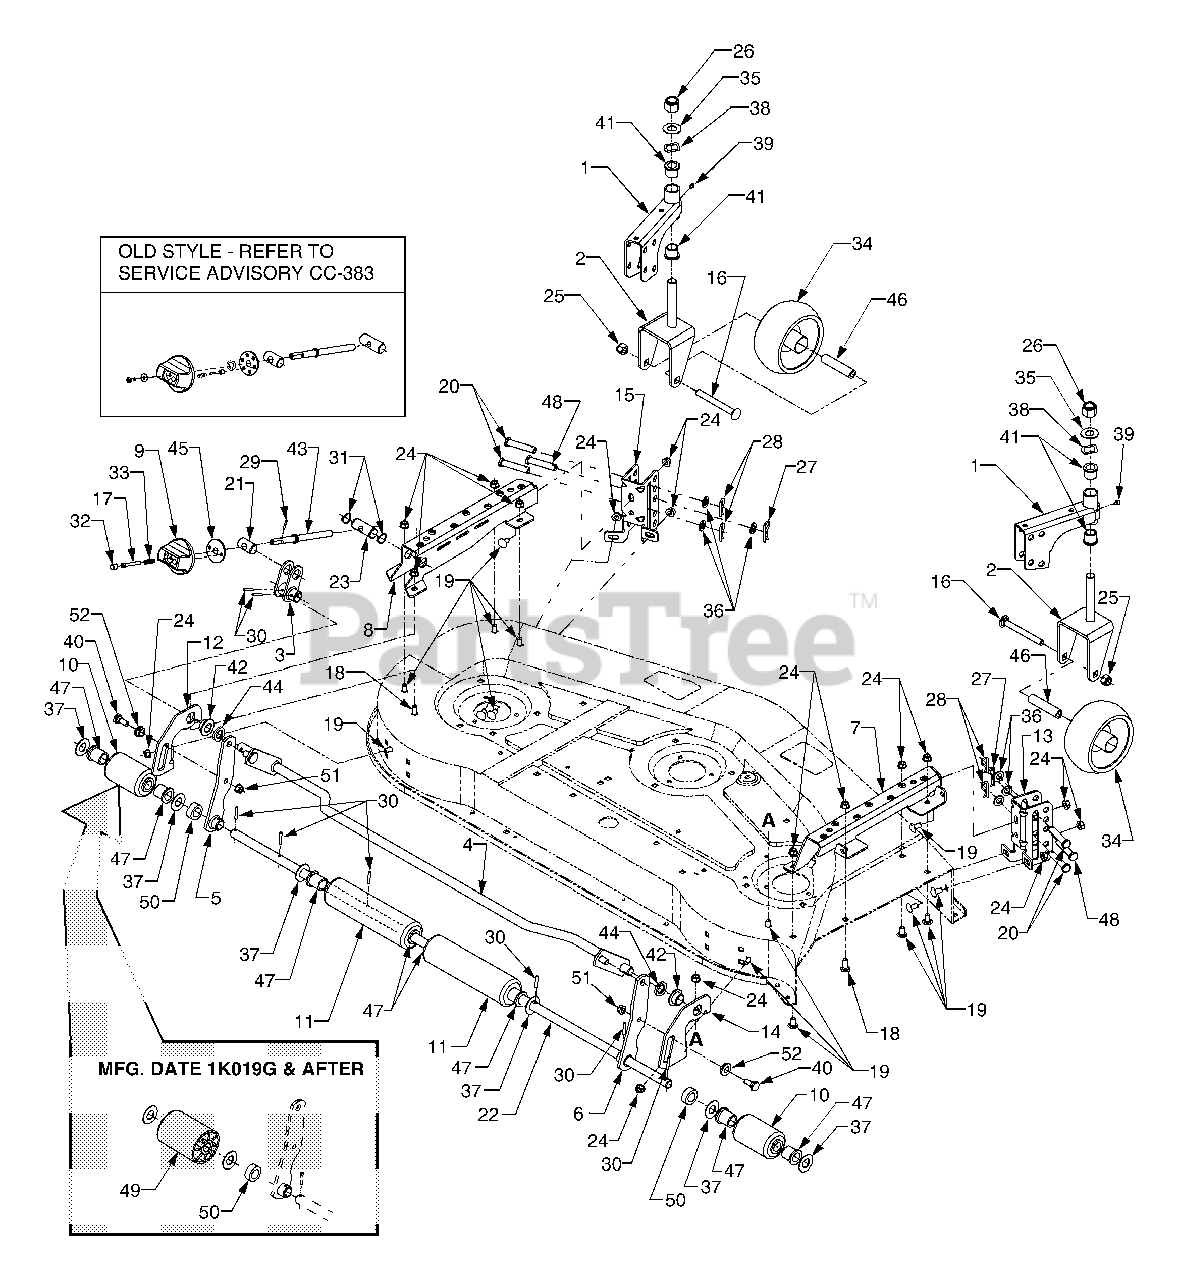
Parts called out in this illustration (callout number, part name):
1	Assembly, Arm - Caster Wheel
2	Assembly, Yoke - Caster Wheel
6	Assembly, Pivot Link (R.H.)
7	Assembly, Brace (R.H.)
8	Assembly, Brace (L.H.)
9	Assembly, Knob w/detent pin
10	Roller, (Short)
11	Roller, (Long)
12	Bracket, Guide (L.H.)
13	Bracket, Height Adjuster (R.H.)
14	Bracket Guide (R.H.)
15	Bracket, Height Adjuster (L.H.)
16	Bolt, Carriage 1/2-13 x 4.5"
17	Screw, Socket Hd Lock 1/4-20 x 2.0
18	Bolt, Carriage 3/8-16 x 1"
19	Bolt, Carriage 3/8-16 x .75"
20	Pin, Clevis
21	Ferrule, Adjustable
22	Axle, Roller
23	Ferrule, Adjust. Thrd, 1/2-13
24	Nut, Flanged Nut 3/8-16
25	Nut, Hex Lock 1/2-13
26	Nut, Hex Lock 3/4-10
27	Pin, Internal Cotter
28	Pin, Internal Cotter
29	Pin, Spirol, .125 x .812
30	Pin, Roll 3/16" Dia. x 1.1"
31	Ring, External Retaining
32	Cap, Tube
33	Spring, Compression
34	Caster, Wheel w/Bearings
35	Washer, Flat .76" I.D.
36	Washer, Flat .535" I.D.
37	Washer, Flat .78" I.D.
38	Washer, Wave .88" I.D.
39	Fitting, Grease
40	Screw, Shoulder
41	Bearing, Flange .75" I.D.
42	Bearing, Flange .75" I.D.
43	Screw, Adjustable
44	Spacer, .75 ID x 1.25 OD x .175
45	Hub, Spring Detent
46	Axle, Caster Wheel
47	Bearing, Flange .75" I.D. Powdered Metal
48	Pin, Clevis
49	Roller, Deck
50	Spacer, .790 ID x .347 Lg
51	Nut, Flanged Nut 3/8-16
52	Bushing, Sq. Hgt Adjust.
